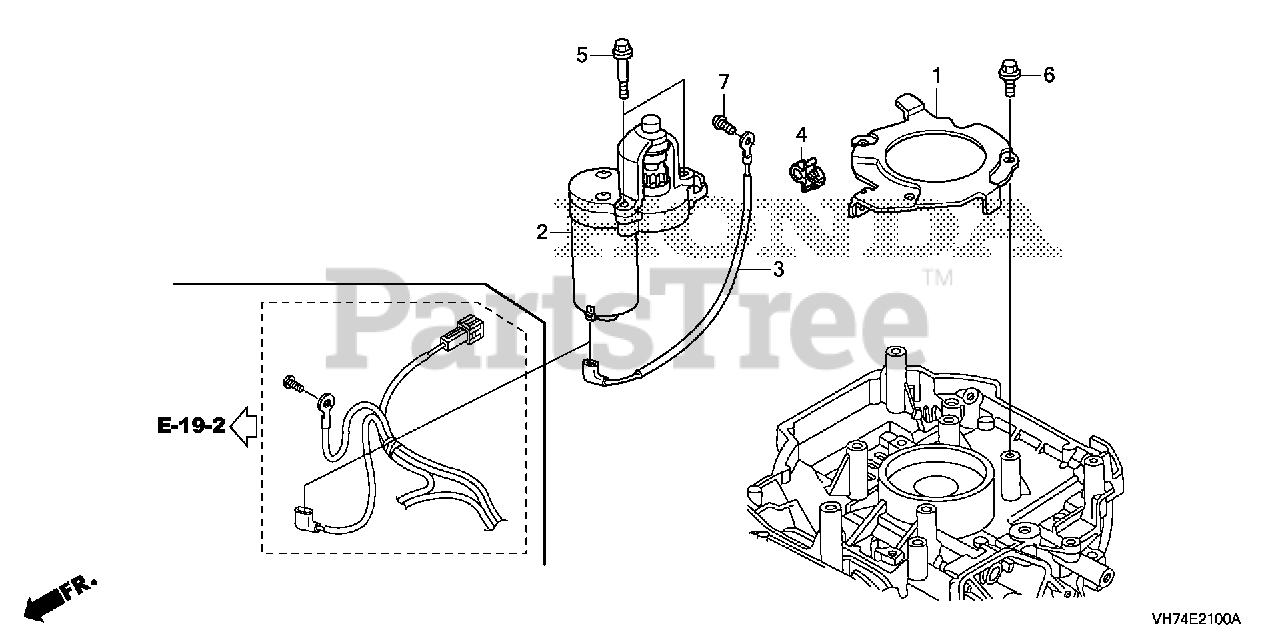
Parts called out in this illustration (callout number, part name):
1	CLAMP, WIRE
2	STARTER MOTOR ASSY.
4	HOLDER, WIRE
5	BOLT, SPECIAL (6MM)
6	BOLT, FLANGE (6X12) (CT200)
